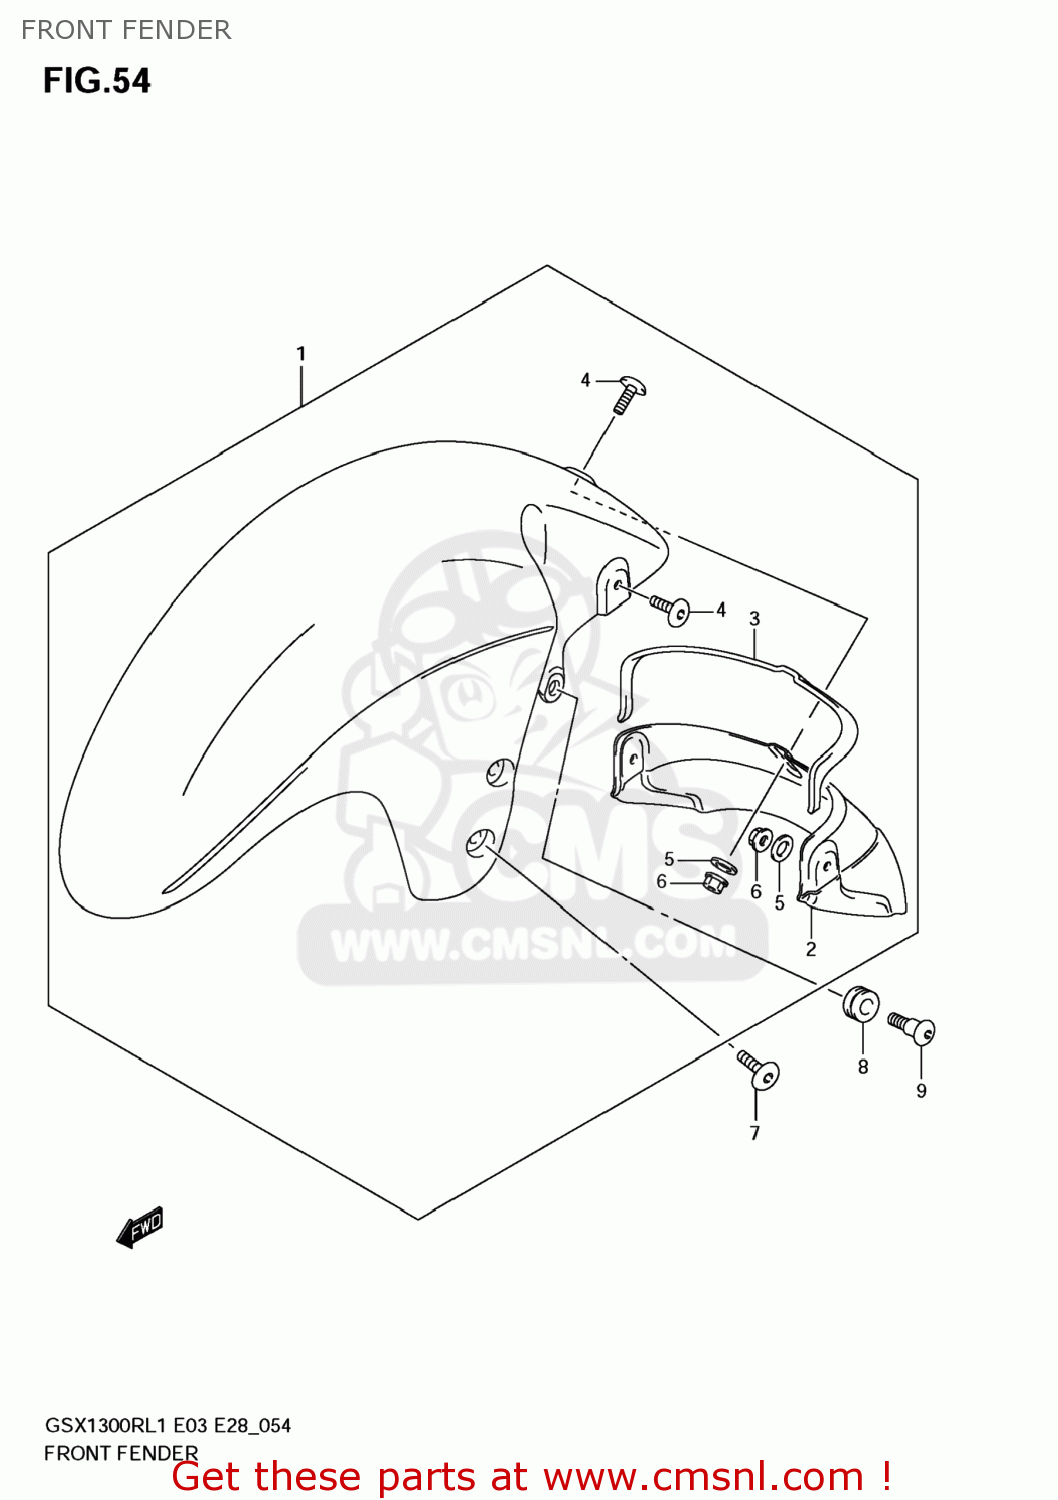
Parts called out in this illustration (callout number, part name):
1	FENDER ASSY,FR(BLUE)
2	MUDGUARD,FR FENDER
3	CUSHION
4	SCREW(6X16)
5	WASHER(6.5X16X1)
6	NUT
7	SCREW(6X16)
8	CUSHION
9	SCREW(6X16)
